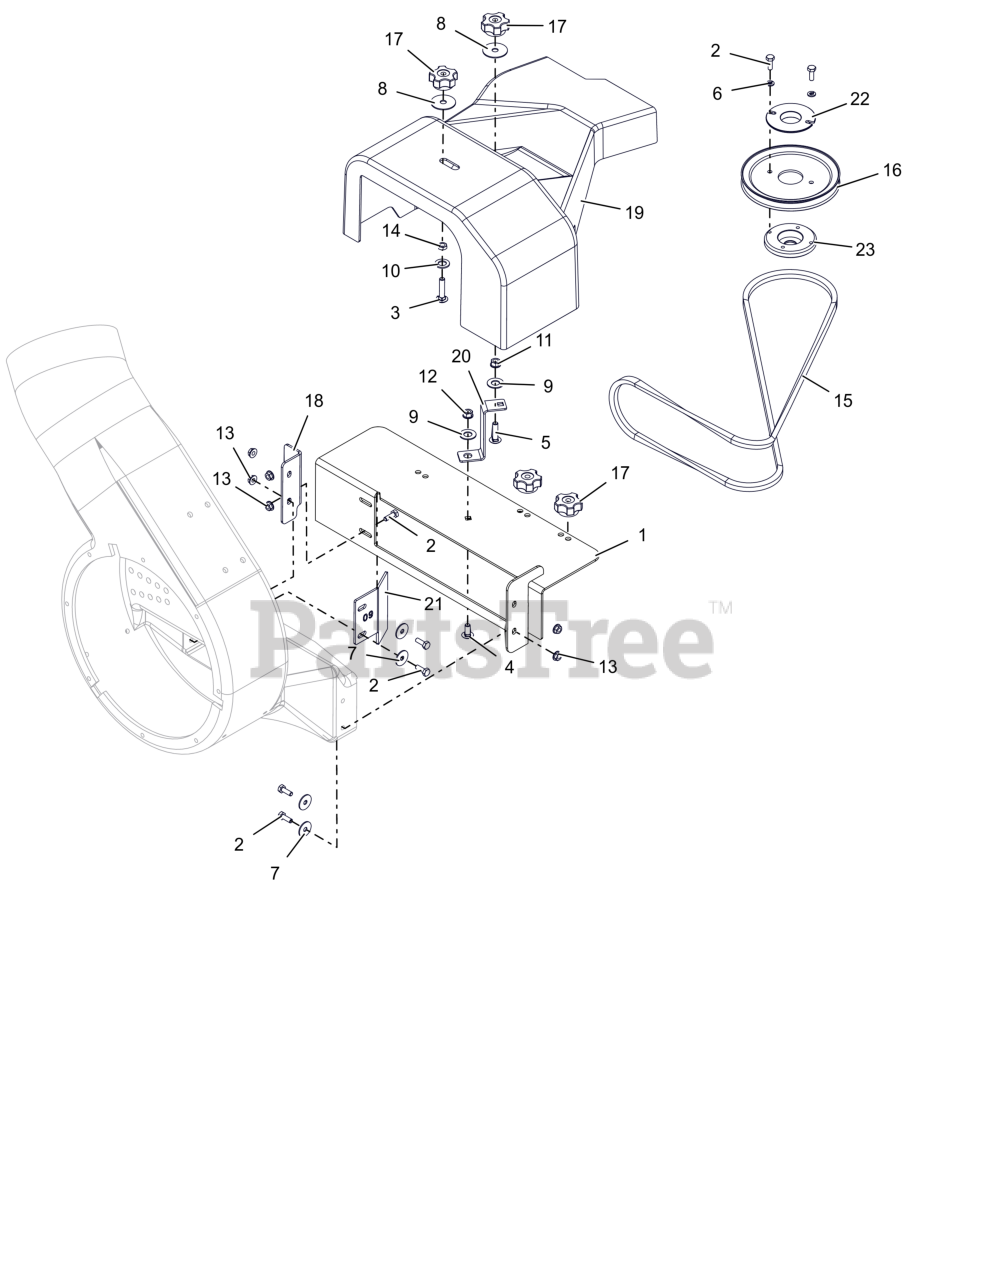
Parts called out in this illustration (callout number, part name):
1	WLDMT, BLT MOUNT BRKT (BLACK)
2	BLT, HEX .25-20X.75 G5 ZCC
3	BLT,RHSN .31-18X1.50 G5 ZCC
4	BLT, RHSSN.31-18X.750 G5 ZCC
5	BTL,RHSSN .313-18 X 1.25 G5 ZCC
6	WSHR,LK-REG .250X.062 ZCC
7	WSHR,FLT .281X1.000X.063 ZCC
8	WSHR,FLT .380X1.50X.062 ZCC
9	WSHR, FLT .505X1.00X.062 ZCC
10	WSHR, FLT .505X.880X.072 ZCC
11	NUT,SPNLK-FLG .31-18 G5 ZCC
12	NUT,LK-CTR-FLG .31-18 GF ZCC
13	NUT-LK-TOP-FLG .250-20 GF ZCC
14	NUT-JAM .312-18 G2 ZCC
15	V-BELT, 4L-RAW EDGE
16	PULLEY,V-6.00OD X1.51 ID CZ120
17	KNOB-CLAMPING, .312-18 NYLOC
18	BRKT, ANGLE SUPPORT (BLACK)
19	GUARD- 60" BLOWER BELT
20	BRKT, BLOWER GUARD MTG
21	BRKT, 60" BLOWER CLOSE OFF (BLACK)
22	ADAPTOR, PULLEY SHEAVE
23	ADAPTER- PULLEY IKON
